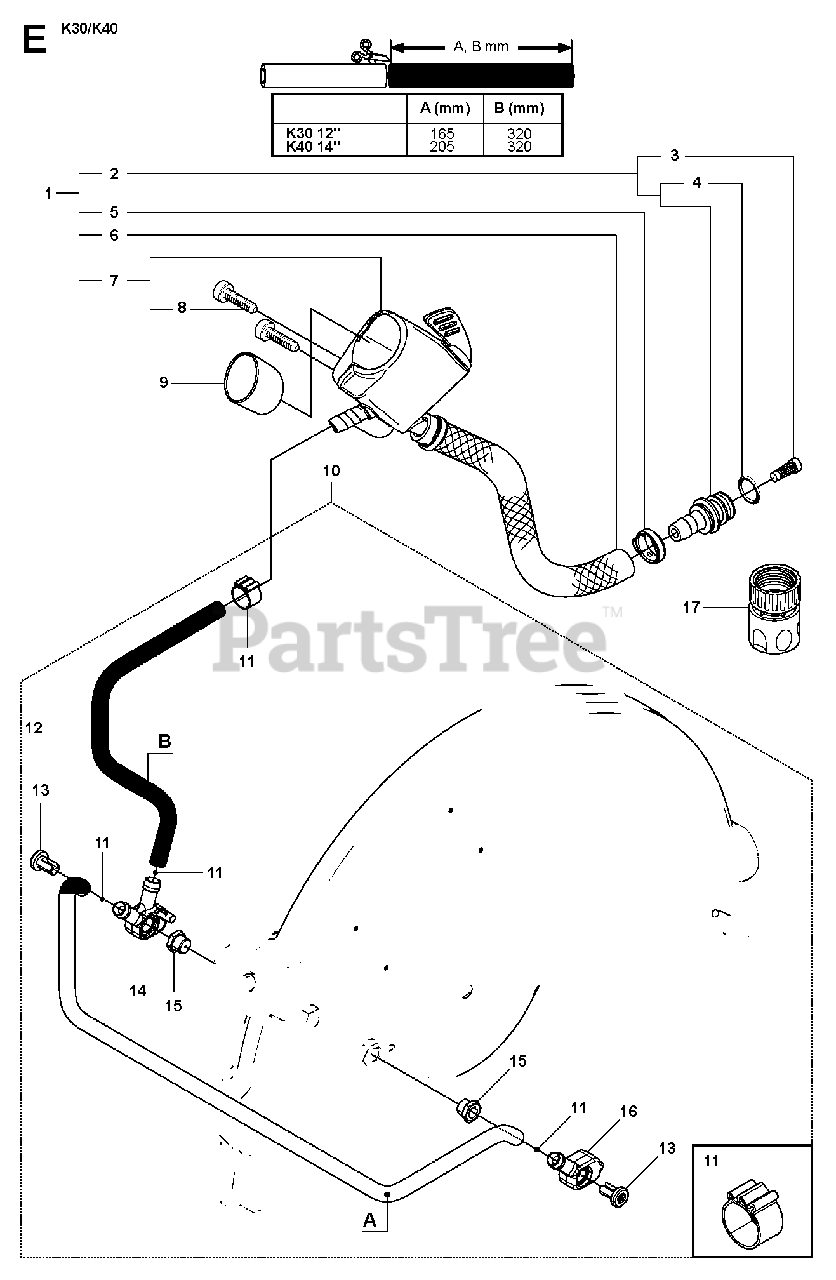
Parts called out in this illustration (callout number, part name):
1	HOSE KITIncl. 2, 5 - 7
2	NIPPLEIncl. 3, 4
5	HOSE CLAMP
7	VALVE ASSYIncl. 8
8	SCREW ITXSCT
10	HOSE KITIncl. 11 - 16
12	HOSE320 mm
13	SCREW ITXSCM
